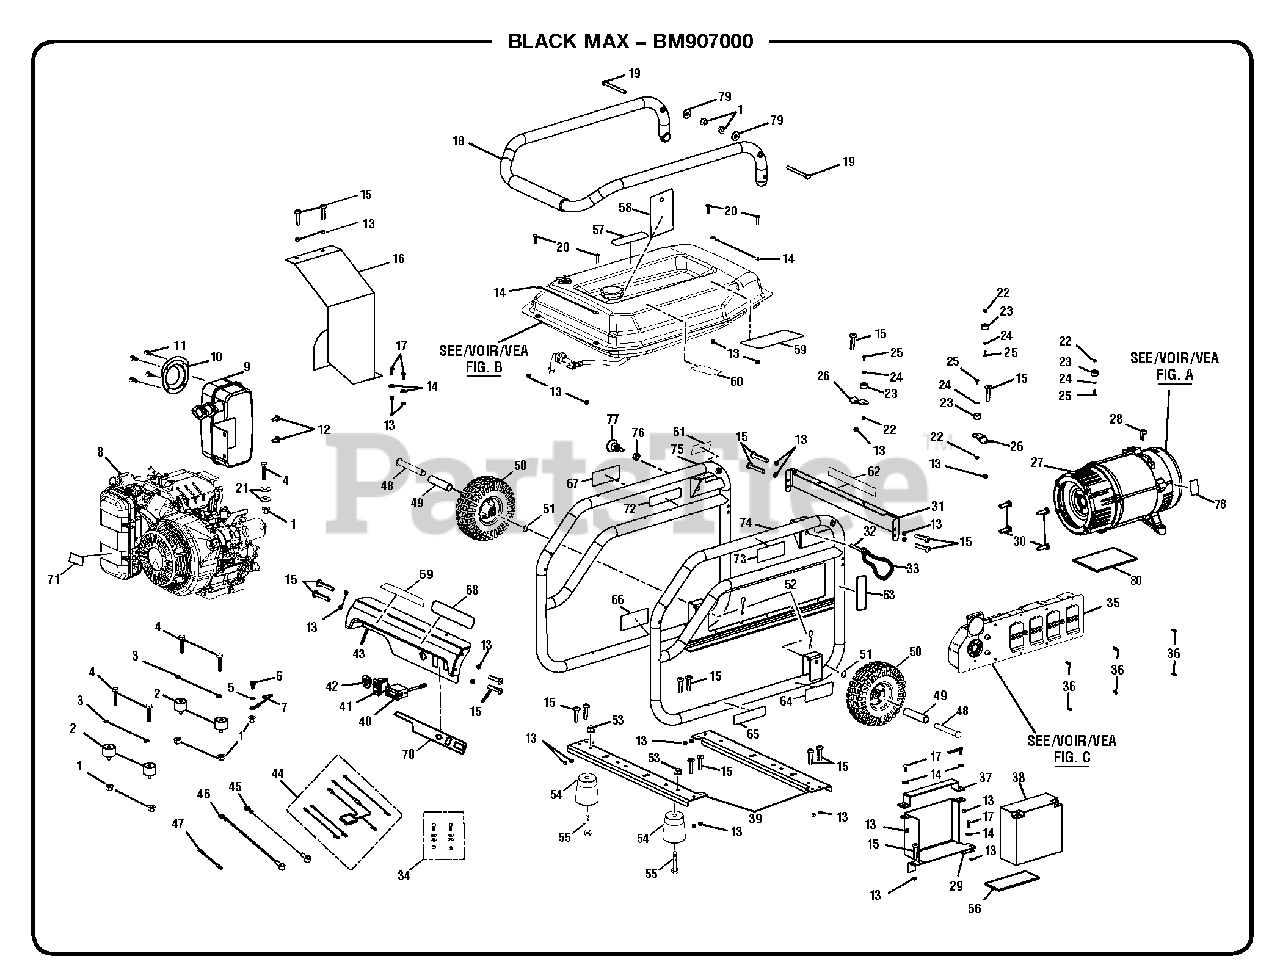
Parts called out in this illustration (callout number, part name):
1	Lock Nut (M8 x 1.25 in.)
3	Washer (M8)
4	Bolt (M8 x 35 mm, Hex Hd.)
5	Star Washer (M8)
6	Bolt (M8 x 15 mm)
7	Ground Wire Assembly
10	Spark Arrestor
11	Screw (8-32 x 3/8 in.)
12	Bolt (5/16-24 x 0.6 in.)
13	Lock Nut (M6)
14	Washer (M6)
15	Screw (M6 x 50 mm, Torx Hd.)
16	Heat Shield
17	Bolt (M6 x 16 mm)
18	Handle Assembly
19	Handle Pivot Bolt (M8 x 98 mm, Flat Hd.)
20	Bolt (M6 x 25 mm, Torx Hd. T30)
21	Washer (5/16 in.)
23	Rubber Bumper
24	Washer (M4)
25	Screw (M4 x 12 mm)
26	Handle Rest Tab
27	Generator Head w/AVR
28	Ground Lug
29	Battery Tray
30	Bolt (3/8-16 x 1 in.)
31	Fuel Tank Support (Back)
32	Handle Lock Pin
34	Fastener Kit (Wiring)
35	Control Panel Assembly
36	Screw (6-20 x 3/8 in., Pan Hd.)
37	Battery Bracket
38	Battery
39	Frame Crossbar
40	Hour Meter
41	Engine Switch
42	Fuel Valve
43	Fuel Tank Support (Front)
44	Wiring Harness
45	Battery Cable (Black)
46	Battery Cable (Red)
47	Bonding Wire
51	Washer (M10)
52	Hitch Pin
53	Lock Nut (M8 x 1.25)
54	Rubber Foot
55	Bolt (M8 x 45 mm, Hex Hd.)
57	CPSC Label
58	Warning Hangtag
59	Danger Label
60	E85 Label
61	Handle Release Label
62	Ground Warning Label
63	Lock Pin Label
64	Inquiries Label
65	Lubricant Label
66	Combustion Label
67	Fire Distance Label
68	Logo Label
69	Black Max Label
70	Start Label
71	Electric Start Label
72	Hot Surface Label
73	Fire Danger Label
74	Frame (Right)
75	Frame (Left)
76	Hex Jam Nut (1/2-20)
77	Handle Release Pin
78	Ground Label
79	Washer (1/4 in.)
